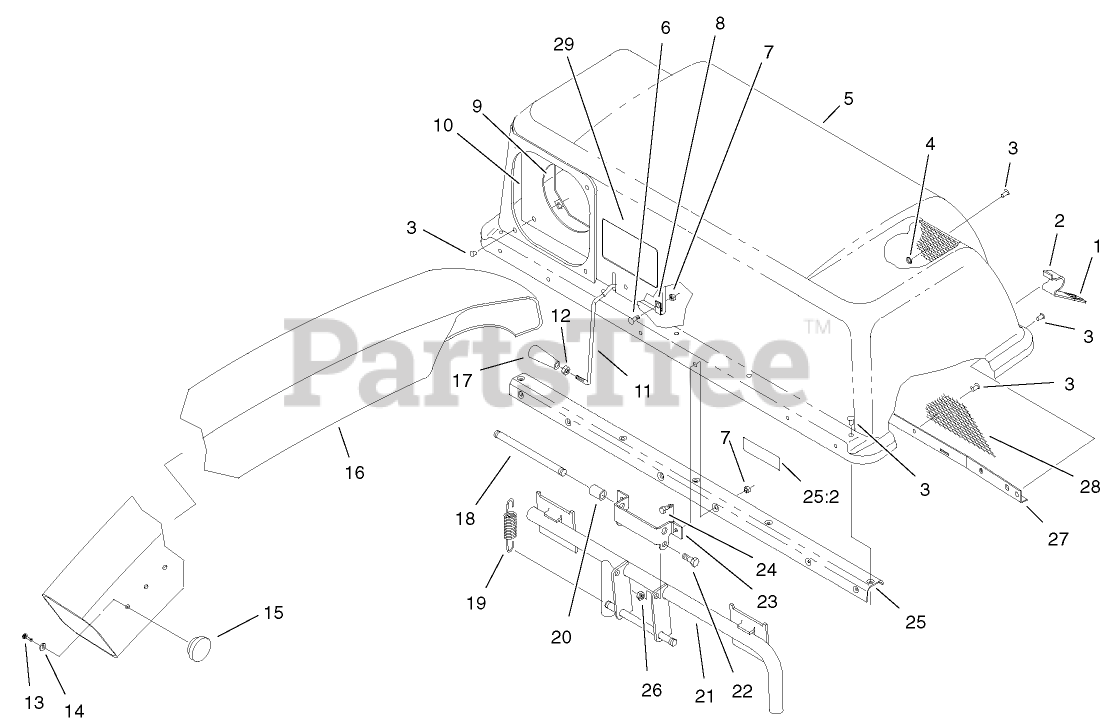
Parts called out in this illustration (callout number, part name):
2	LATCH-BAGGER, TOP
3	RIVET-BLIND
4	WASHER-FLAT
5	TOP-BAGGER
6	SCREW-PPH
7	NUT-LOCK, NI
8	CLAMP
9	CLAMP-SEAL
10	SEAL-CHUTE
11	FEELER-FILL, BAG
12	NUT-JAM
13	SCREW-PPHTF
14	WASHER-PLAIN
16	CHUTE-DISCHARGE
17	HANDLE-TAPERED
18	PIN-SPRING
19	SPRING-EXTENSION
20	SPACER
21	FRAME ASM
22	SCREW-HH
23	HINGE-BAG, TOP
24	SCREW-HH
25	STIFFENER ASM
25:2	DECAL-CAUTION
26	NUT-LOCK, NI
27	SUPPORT-SCREEN
28	SCREEN-BAGGER
29	DECAL
